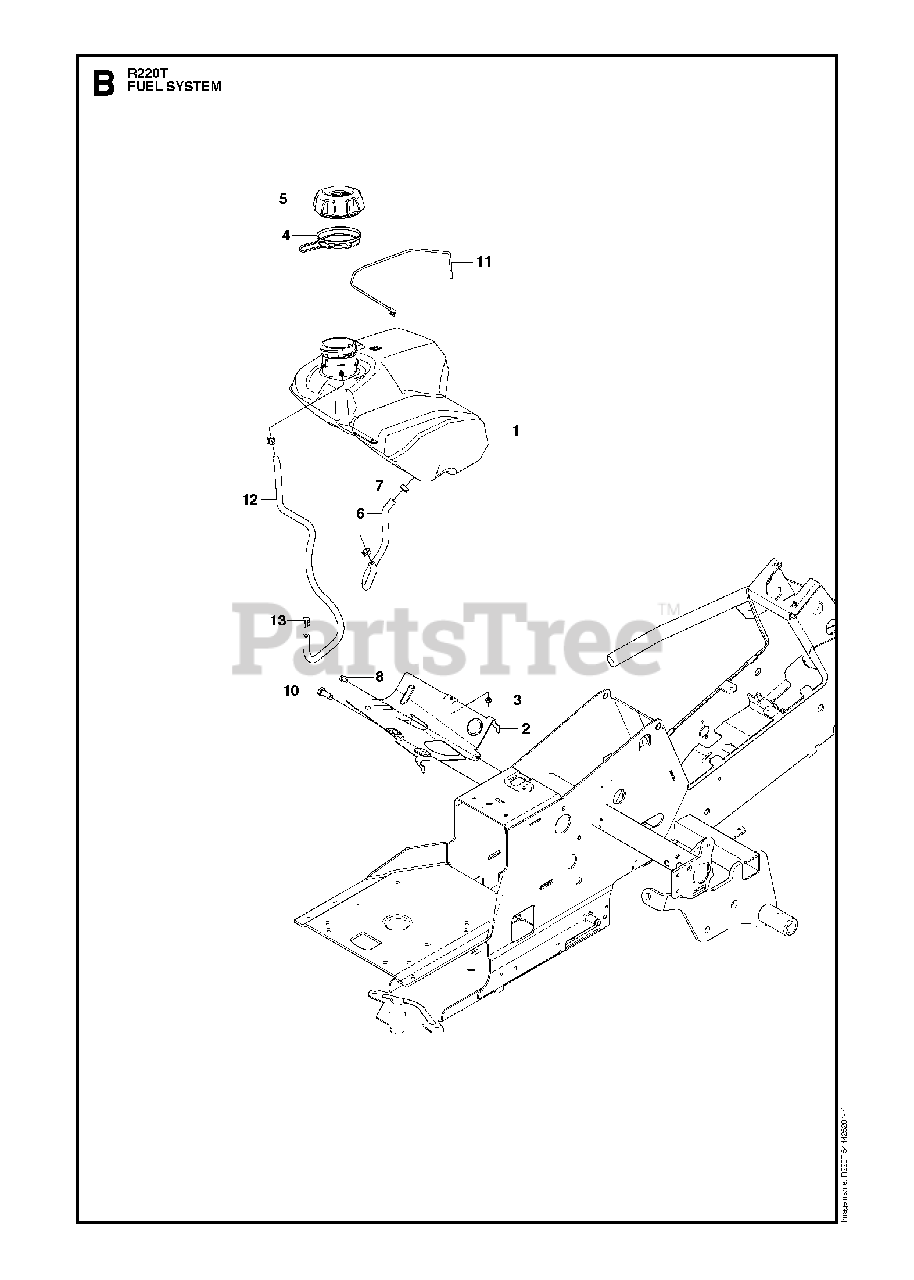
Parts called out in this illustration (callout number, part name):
3	LOCKNUT M6
4	HOSE CLAMP
5	CAP.ASM.FL.RITCH.3"E10.SYM.498
10	Screw, M10 X 25
13	HOSE CLAMP
